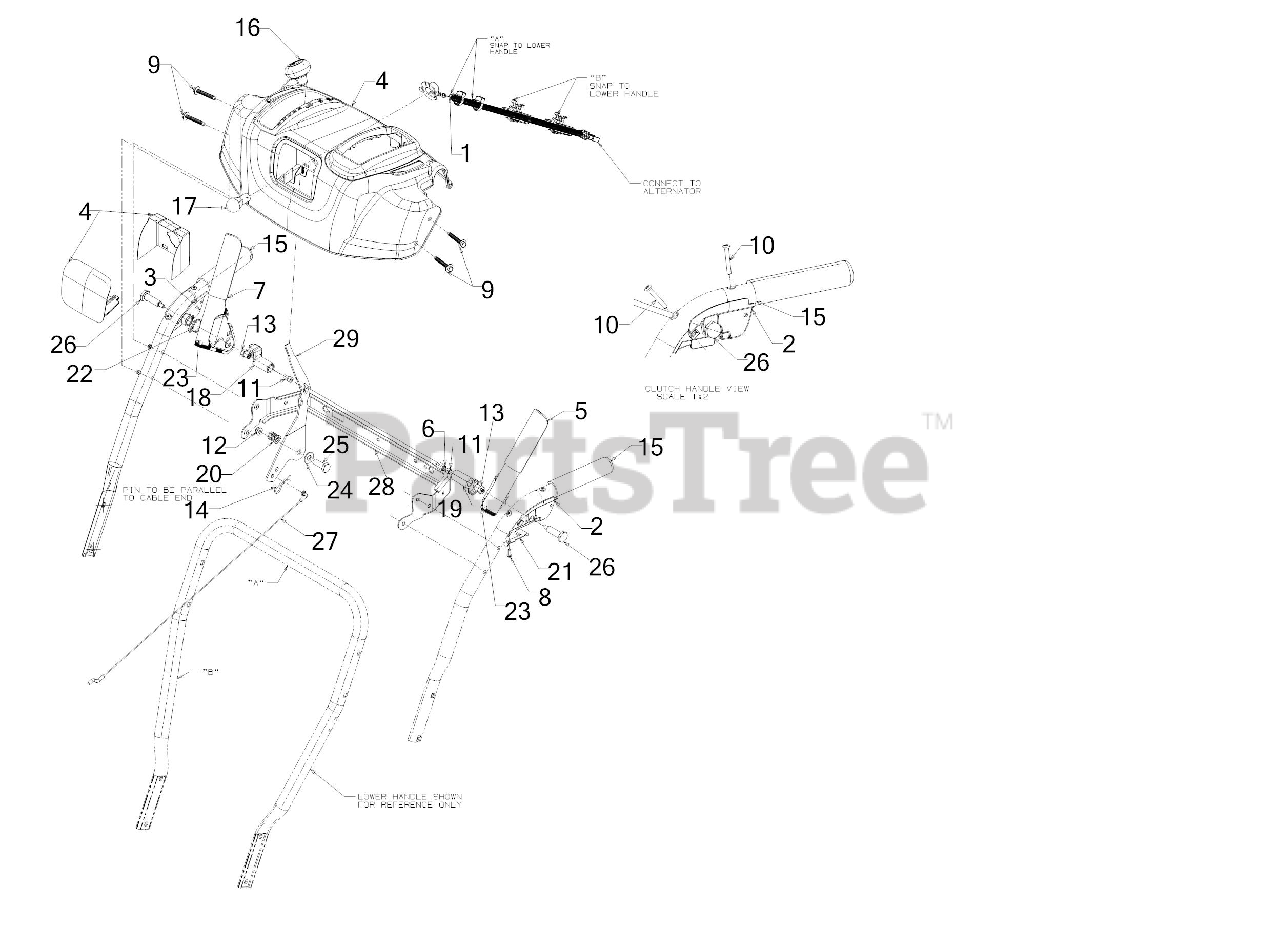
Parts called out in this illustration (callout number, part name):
1	LIGHT HARNESS
1	HEADLIGHT SOCKET
2	CLUTCH LOCK HANDLE ASSEMBLY (LH)
3	CLUTCH LOCK HANDLE ASSEMBLY (RH)
4	HANDLE PANEL ASSEMBLY (BLACK)
5	HANDLE ASSEMBLY (LH)
6	PIVOT ROD
7	ENGAGEMENT HANDLE ASSEMBLY (RH) (BLACK)
8	SCREW #8-16 x .50
9	SCREW 1/4-20 x 1.625
10	SCREW #10-24 x 1.375
11	SCREW 1/4-20 x .50
12	FLANGE LOCK NUT
13	HEX NUT W/PATCH
14	INTERNAL COTTER PIN
16	SHIFT KNOB
17	LAMP-#1683
18	LOCK PLATE
19	CLUTCH LOCK CAM
20	COMPRESSION SPRING
21	CLUTCH SPRING
22	TORSION SPRING
23	RUBBER BUMPER
24	FLAT WASHER
25	SHOULDER SCREW
26	SHOULDER SCREW .437 x 1.345 1/4-20
27	SPEED SELECTOR CABLE (PLASTIC)
28	HANDLE SUPPORT BRACKET
29	SHIFT LEVER
